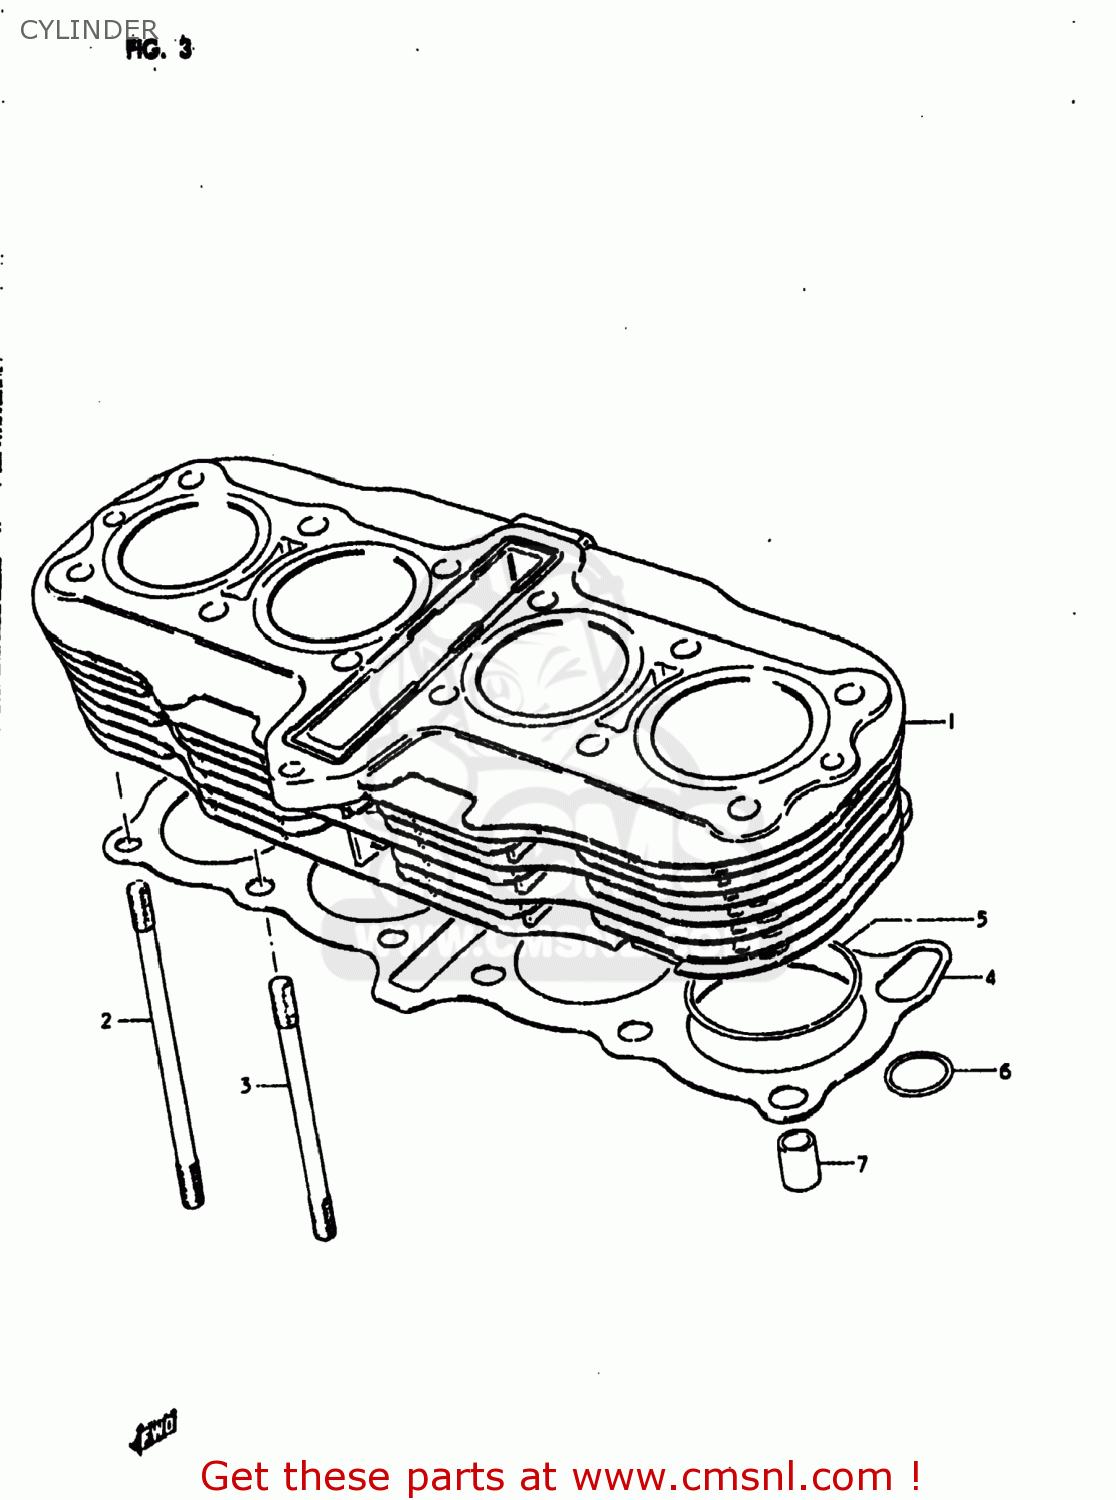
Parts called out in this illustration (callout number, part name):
1	CYLINDER
2	BOLT,STUD
3	STUD
4	GASKET,CYLINDER (MCA)
5	O RING(D:2,ID:74)
6	O RING(D:3.05)
7	PIN
